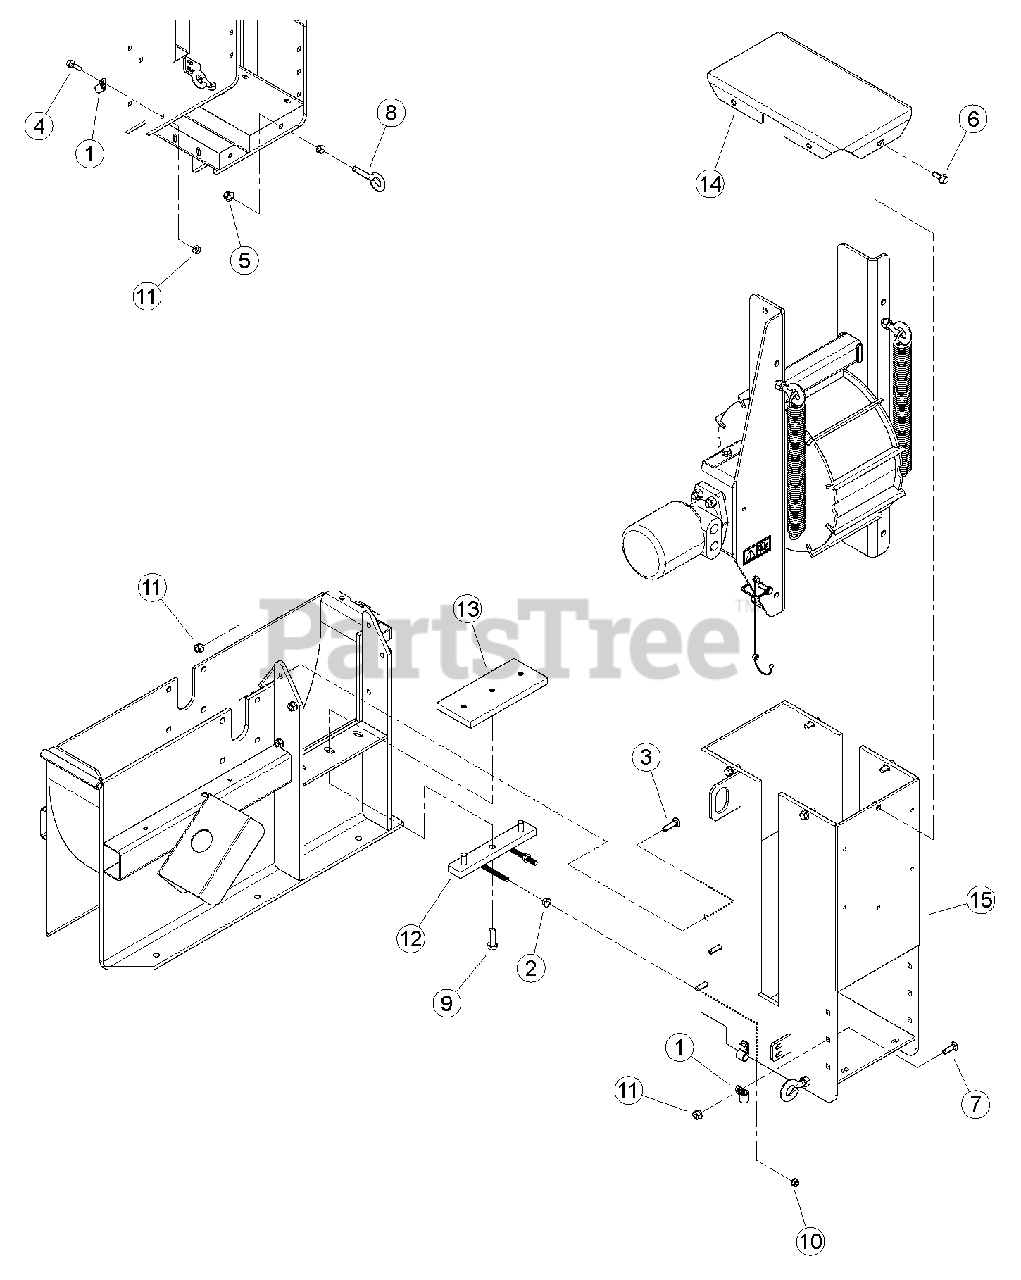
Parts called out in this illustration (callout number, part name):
1	CLAMP, 9/16 COATED
2	NUT, 3/8" SERRATED FLANGE NC ZP
3	BOLT, 3/8 X 1-1/2" GR5 CRG NC ZP
4	BOLT, 3/8 X 1-1/4 FLANGE NC
5	NUT, 1/2-13 NYLOCK FLANGE
6	BOLT, 3/8 X 1 FLANGE NC
7	BOLT, 3/8 X 1-1/4" GR5 CRG NC ZP
8	EYEBOLT, 1/2 X 2" ZP
9	BOLT, 1/2 X 1-1/2 GR8 NC ZP HEX HD
10	NUT, 5/16-18 NYLOCK-FLANGE
11	NUT, 3/8-16 NYLOCK FLANGE
12	WELDMENT, BLOCK ADJUSTOR
13	PLATE, CHIPPER BOTTOM
14	WELDMENT, TOP ROLLER COVER
15	WELDMENT, ROLLER SUPPORT
